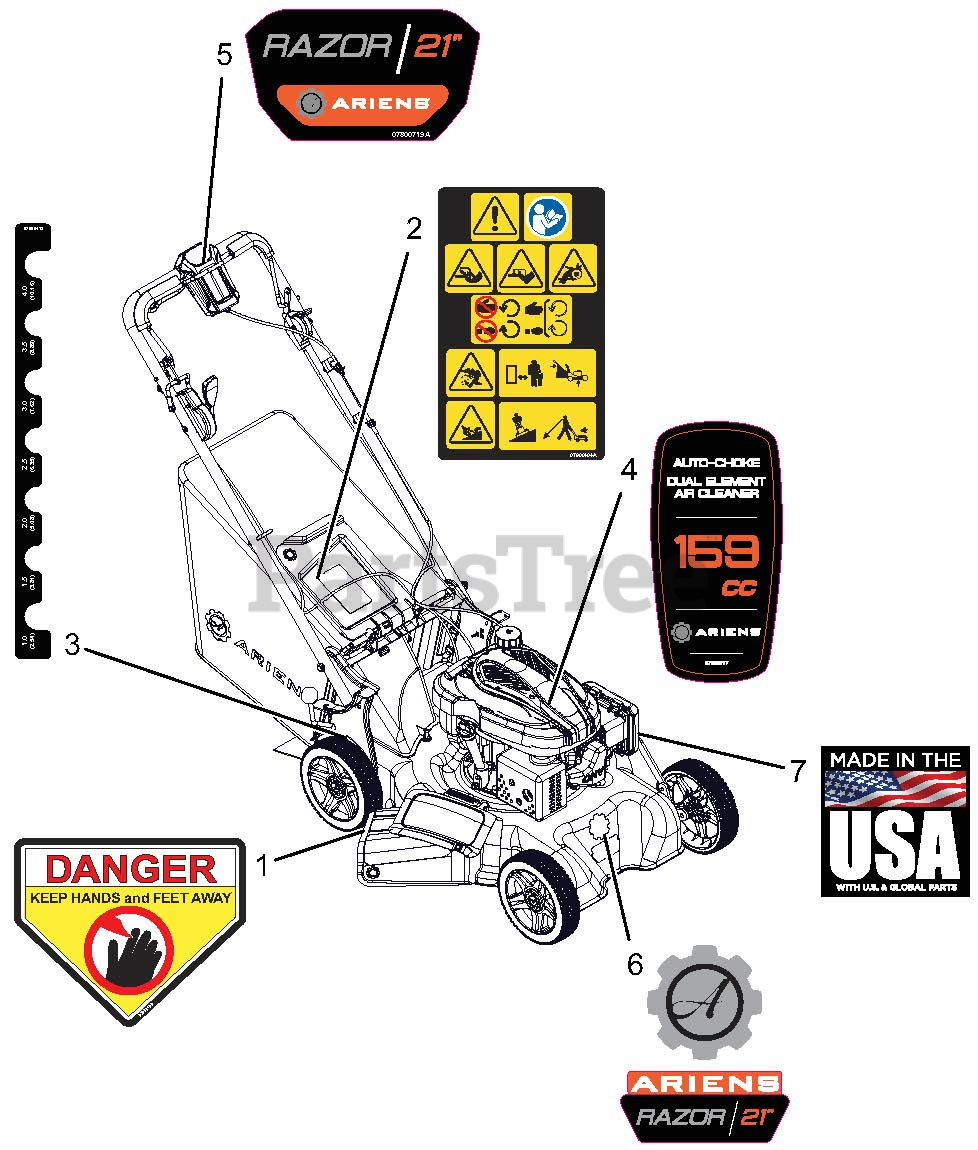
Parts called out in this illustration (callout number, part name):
1	DECAL, DANGER
2	DECAL,MAIN SAFETY_WAW LM
3	DECAL, HOC
4	DECAL-ENGINE STYLE-RAZOR
5	DECAL-CONTROL-RAZOR
6	DECAL-ARIENS RAZOR 21"
7	DECAL, MADE IN USA
